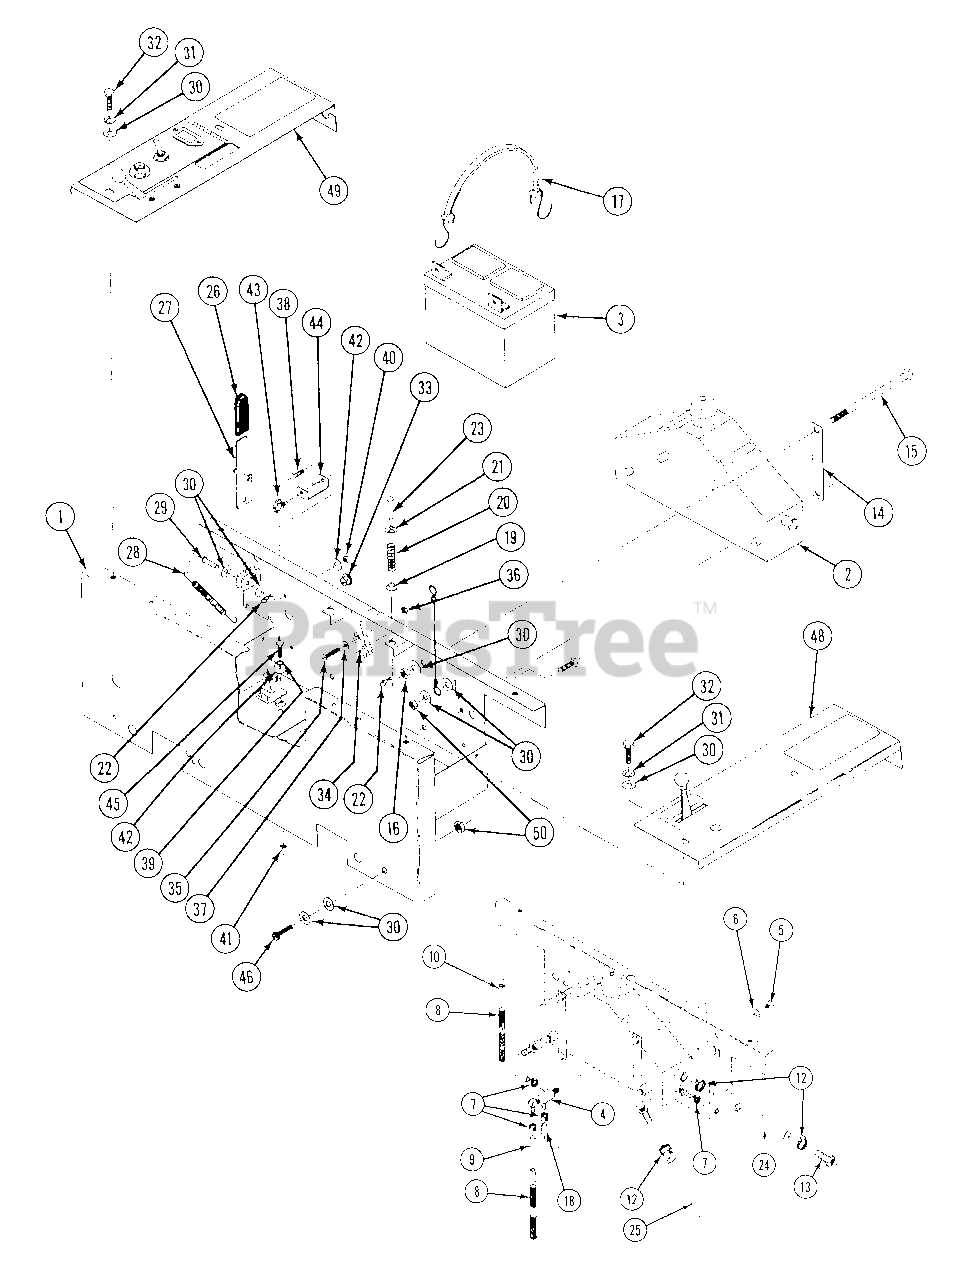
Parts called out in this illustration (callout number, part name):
1	SEAT SUPPORT WELDMENT
2	OIL TANK ASSEMBLY
3	BATTERY
4	BRAKE VALVE ASSEMBLY
5	LOCKWASHER, INTERNAL STAR: 5/8
6	NUT, HX: 5/8-11
7	CLAMP, HOSE: 1/4 ID
8	SHIELD, CABLE
9	HOSE, RIGHT BRAKE
10	HOSE, LEFT BRAKE
12	CLAMP, HOSE: 3/4 ID
13	HOSE BARB, 3/4 X 7/8 SAE PORT
14	OIL TANK STRAPS
15	CAPSCREW, HX HD: 3/8-16 X 5 GR 5
16	LOCKNUT, NYLOCK: 3/8-16
17	STRAP, 12 IN. RUBBER TIE DOWN
18	HOSE, BRAKE RETURN
19	BUSHING, NYLON SEAT SPRING
20	SPRING, COMPRESSION
21	BUSHING, STEEL SEAT SPRING
22	RUE PIN
23	PIN, CLEVIS: 5/16 X 1-3/4
24	HOSE, UNISTAT RETURN
25	HOSE, UNISTAT INLET
26	GRIP, HANDLE
27	BRAKE HANDLE WELDMENT
28	SPRING, EXTENSION
29	PIN, CLEVIS: 5/16 X 1
30	FLAT WASHER: 5/16
31	LOCKWASHER, SPLT SPRNG: 5/16
32	CAPSCREW, HX HD: 5/16-18 X 1 GR 5
33	BUSHING, 7/8 PLASTIC
34	SWITCH, SEAT
35	SCREW, MACH: 6-32 X 1
36	LOCKNUT, NYLOCK: 6-32
37	LOCKWASHER, INTERNAL STAR: NO.6
38	CAPSCREW, HX HD: 1/4-20 X 1 GR 5
39	LOCKWASHER, SPLT SPRNG: 1/4
40	LOCKNUT, STOVER: 1/4-20
41	LOCKNUT, NYLOCK: 1/4-20
42	FLAT WASHER: 1/4
43	ROSEBUD CLIP: 1/2
44	STAND-OFF
45	CAPSCREW, HX HD: 1/4-20 X 3/4 GR 5
46	CAPSCREW, SKT HD: 5/16-18 X 1 GR 8
48	FENDER CAP ASSEMBLY, LH
49	FENDER CAP ASSEMBLY, RH
50	LOCKNUT, NYLOCK: 5/16-18
